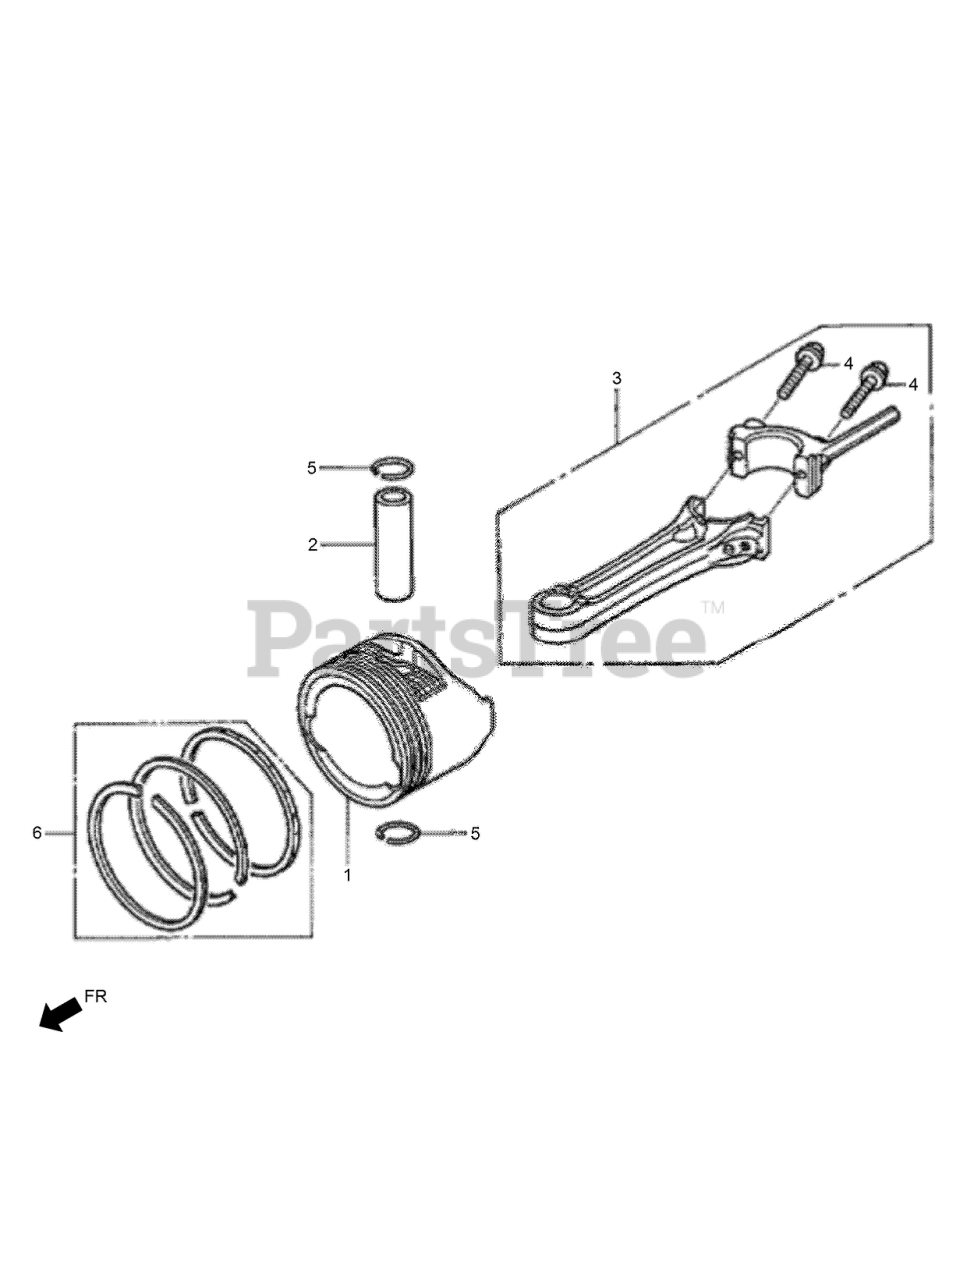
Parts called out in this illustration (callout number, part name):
1	PISTON
2	PIN-PISTON (from S/N 3381418)
2	PIN-PISTON (to S/N 3381417)
3	ROD ASM-CONNECTING
4	BOLT-CONNECTING ROD
5	CLIP-PISTON PIN-13MM
6	RING SET-PISTON (STD)
